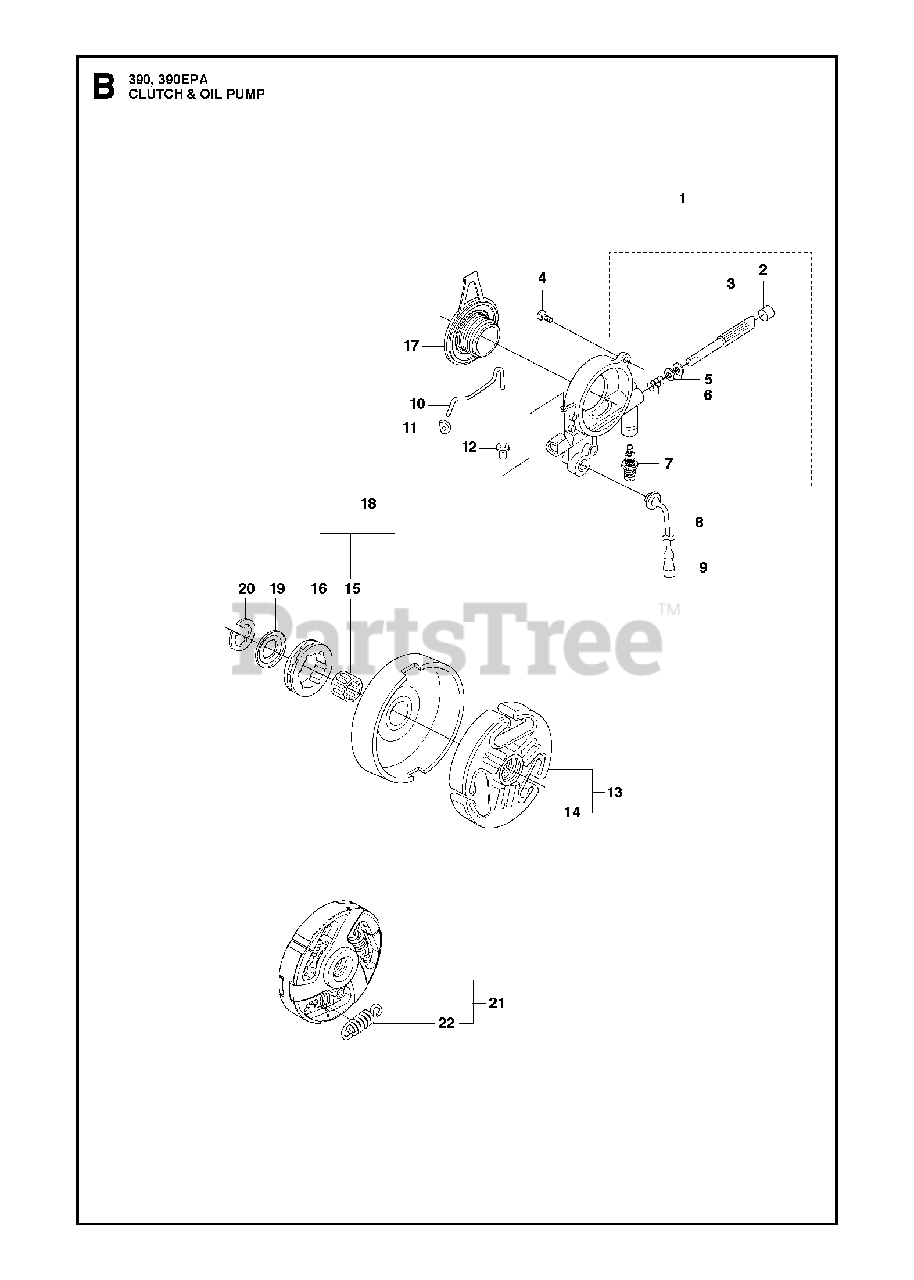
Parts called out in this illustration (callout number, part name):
2	PLUG
3	PUMP PISTON
4	SCREW MC6S 5X16
5	WASHER 6.1X9
6	SPRING
7	INSERT OIL PUMP
9	OIL SCREEN
13	CLUTCH
14	CLUTCH SPRING
15	CLUTCH DRUM BEARING
16	68210 RIMSPROCKET
16	Power Mate Rim
16	22270 RIMSPROCKET
17	PINION
18	CLUTCH ASSY
18	CLUTCH DRUM ASSY .404
20	RETAINING RING
21	CLUTCH ASSEMBLY
22	CLUTCH SPRING
